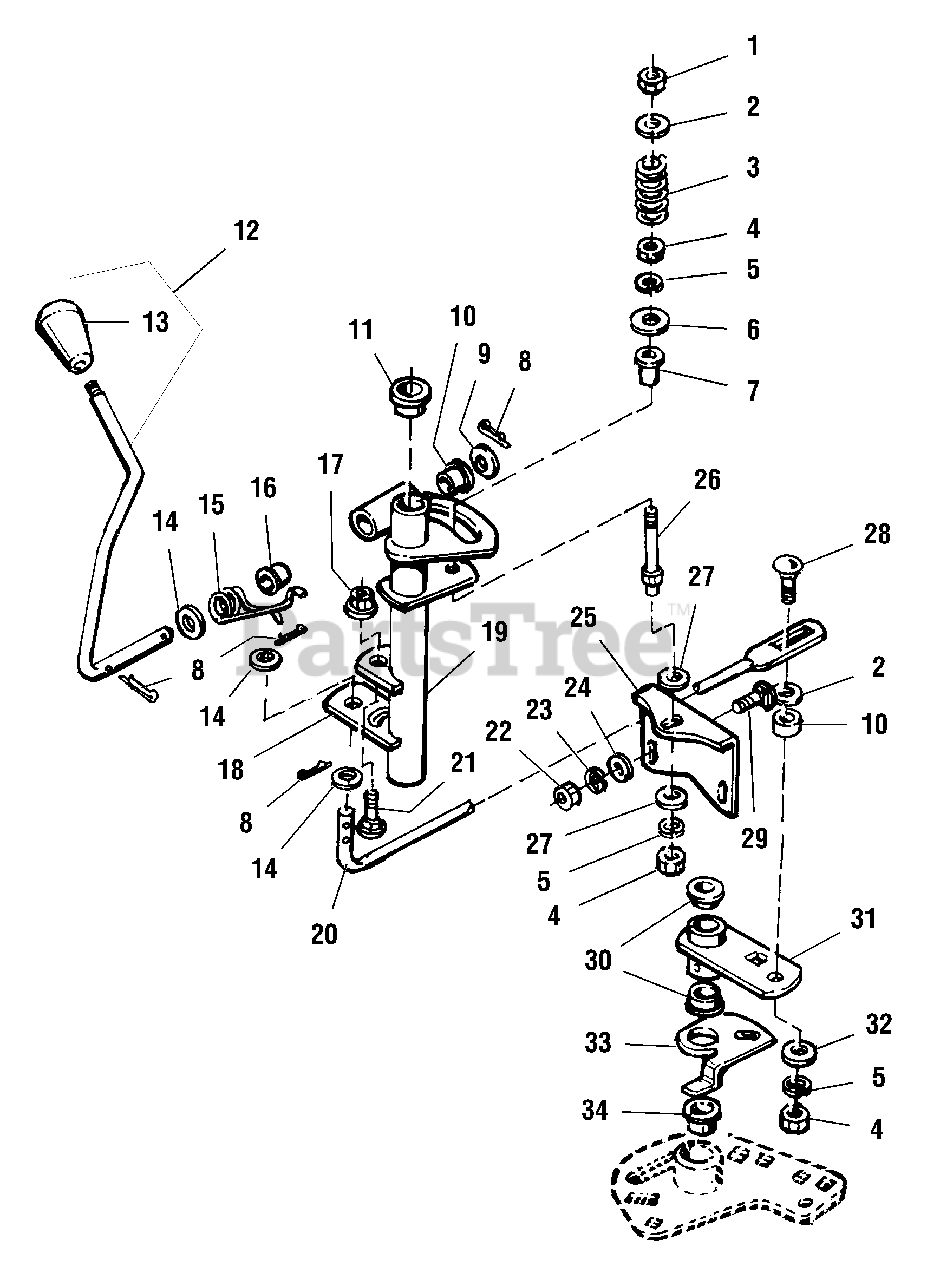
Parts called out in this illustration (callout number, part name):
1	NUT, Hex, Nylon Lock, 5/16-18
2	WASHER
4	NUT, Hex, Full, 5/16-18
5	LOCKWASHER, 5/16
6	WASHER, Special
8	COTTER PIN
11	BUSHING, Plastic, 3/4
12	LEVER, Shift
13	KNOB, Shift Lever
14	WASHER
15	SPRING, Torsion
16	BUSHING, Plastic, 1/2
17	NUT, Hex, Flange Lock, 3/8-16
18	LEVER, Shift Adjuster
19	SHIFT LEVER ASSY.
20	SHIFT ROD, Front
21	CARRIAGE BOLT, 3/8-16 x 1
22	NUT, Hex, Full, 1/4-20
23	LOCKWASHER, 1/4
24	WASHER, Plain, 1/4
25	BRACKET, Tension
28	CARRIAGE BOLT, 5/16-18 x 1-1/4
29	CARRIAGE BOLT, 1/4-20 x 3/4
30	BUSHING, Plastic
31	PIVOT ASSY., Shift
32	WASHER, Plain, 5/16
33	LEVER, Lockout
34	BUSHING, Plastic
